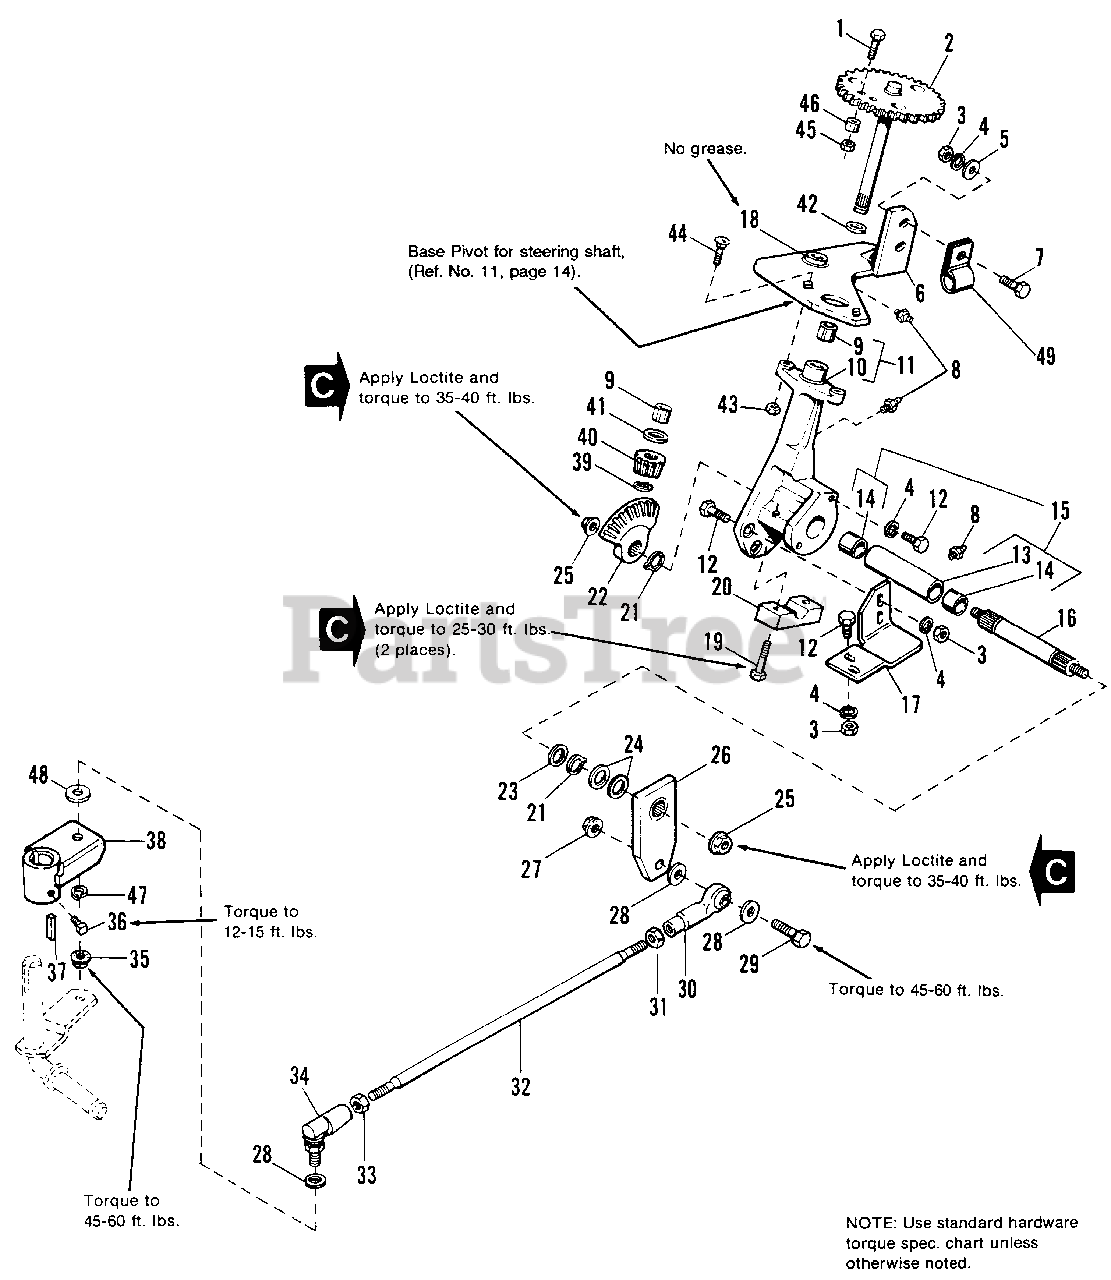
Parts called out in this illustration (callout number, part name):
1	CAPSCREW, Hex Hd., 5/16-18 x 1-1/4
2	SHAFT & GEAR ASSY. (76 Teeth)
3	NUT, Hex, 3/8-16
4	LOCKWASHER, 3/8
5	WASHER, Plain, 13/32
6	PLATE ASSY, Gear w/Bushing (Incl. Ref. No. 18)
7	CAPSCREW, Hex Hd., 318-16 x 1-1/2
8	FITTING, Lube
11	HOUSING, Steering (Incl. Qty. 2 of Ref. Nos. 9 & 10)
12	CAPSCREW, Hex Hd., 3/8-16 x 1
15	TUBE ASSY., Bearing (Incl. Ref. Nos. 13 & 14, Qty. 2)
16	SHAFT, Steering Arm
17	BRACKET, Support
18	BUSHING, Plate Assy., Gear
19	CAPSCREW, Hex Hd., 3/8-16 x 1-3/4
20	CLAMP, Bearing Tube
21	RING, Retainer
22	GEAR, Bevel (14 Teeth)
23	WASHER, 1 x 1-3/8 x 1/16
24	WASHER, 1 x 1-5/8 x 1/64
25	LOCKNUT, Hex, Flange, 1/2-13
26	ARM ASSY., Steering, Splined
27	NUT, Hex, Jam Centerlock, 1/2-13
28	WASHER, Plain, 17/32 x 3/4 x 5/64
29	CAPSCREW, Hex Hd., 1/2-13 x 1-1/2
31	NUT, Hex, Jam, 1/2-20
32	DRAG LINK
33	NUT, Hex, Jam, 1/2-20
35	NUT, Hex, Centerlock, 1/2-20
36	SETSCREW, Sq. Hd., 5/16-18 x 1/2
37	KEY, Parallel, 1/4 x 1/4 x 1-1/2
38	ARM ASSY., Spindle
39	RING, Retaining, 3/4
40	PINION, Bevel, (14 Teeth)
41	WASHER, Thrust, 1-3/8 O.D.
42	WASHER, Spring
43	LOCKNUT, Hex, 3/8-16
44	BOLT, Carriage, 3/8-16 x 1-1/4
45	NUT, Hex Centerlock, 5/16-18
46	SPACER, Brake
47	LOCKWASHER, 1/2
48	WASHER, Hardened, 1/2 x 1-1/4 x 3/16
49	CLAMP, Insulated
